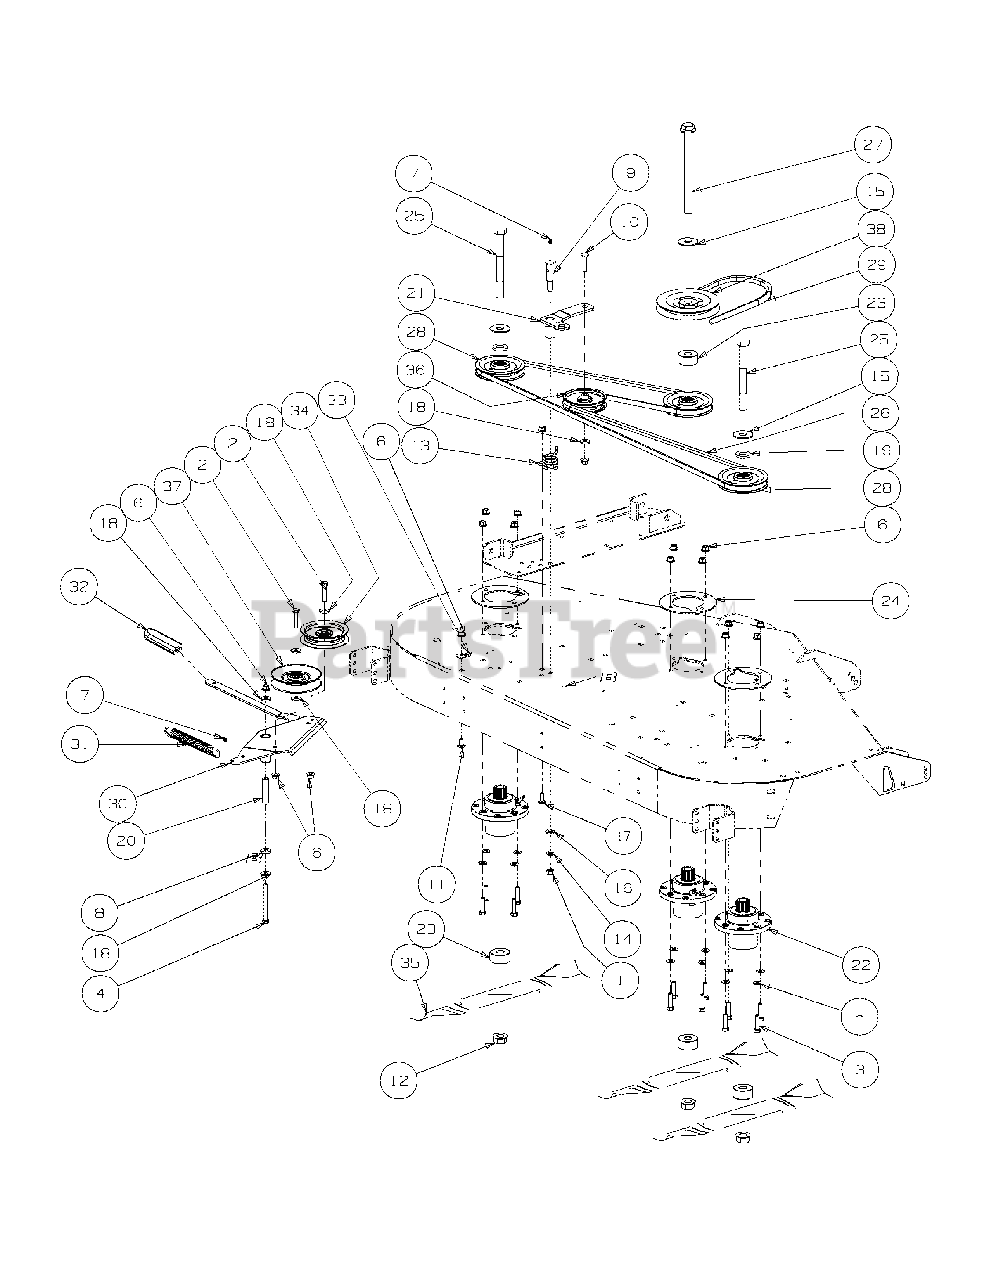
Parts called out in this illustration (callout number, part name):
1	Hex Nut, 7/16-14
2	Hex Cap Screw, 3/8-16 x 1-3/4
3	Hex Cap Screw, 3/8-16 x 1-1/2
4	Hex Cap Screw, 3/8-16, 4.00
5	Flat Washer, 3/8
6	Flange Lock Hex Nut, 3/8-16
7	Grease Fitting, 1/4-28 x 3/16
8	Idler Washer
9	Shoulder Screw, 7/16-14
10	Hex Carriage Screw, 3/8-16, 1.75
11	Carriage Bolt, 3/8-16 x .75 Lg.
12	Flange Hex Nut, 3/4-16
13	Torsion Idler Spring
14	Lock Washer, 7/16
15	Flat Washer, .781 ID 2.00 OD, .105
16	Flat Washer, .469 ID, .875 OD, .105
17	Carriage Bolt, 3/8-16 x 1
18	Flat Washer, .406 ID, 1.0 OD, .105
19	Spacer .812 ID x .268 LG
20	Spacer, .39 ID x .625 OD x 2.75
21	Idler Arm Assembly, Deck Spindle includes:
22	Aluminum Spindle Assembly
23	Spacer, .760 ID x 2.00 OD x 1.1
24	Aluminum Spindle Support Plate
25	Hex Cap Screw, 3/4-16, 7.00
26	V-Belt, A Section x 122.3
27	Hex Cap Screw, 3/4-16, 9.00
28	V-Pulley, 5.00 OD
29	V-Belt, B Section x 147.4
30	Idler Arm Assembly Service Kit
31	Extension Spring, .94 x OD x 7.57
32	Grip, 1.0 x 3.2 x .25
33	Tension Spring Bracket
34	Idler Pulley, 4.06 OD
35	Hi-Lift Blade, 21.0, 0.756 ID
36	Flat Pulley with Flanges
37	Idler Pulley, 5.06 OD
38	V-Pulley, 6.38 OD x .760 ID
